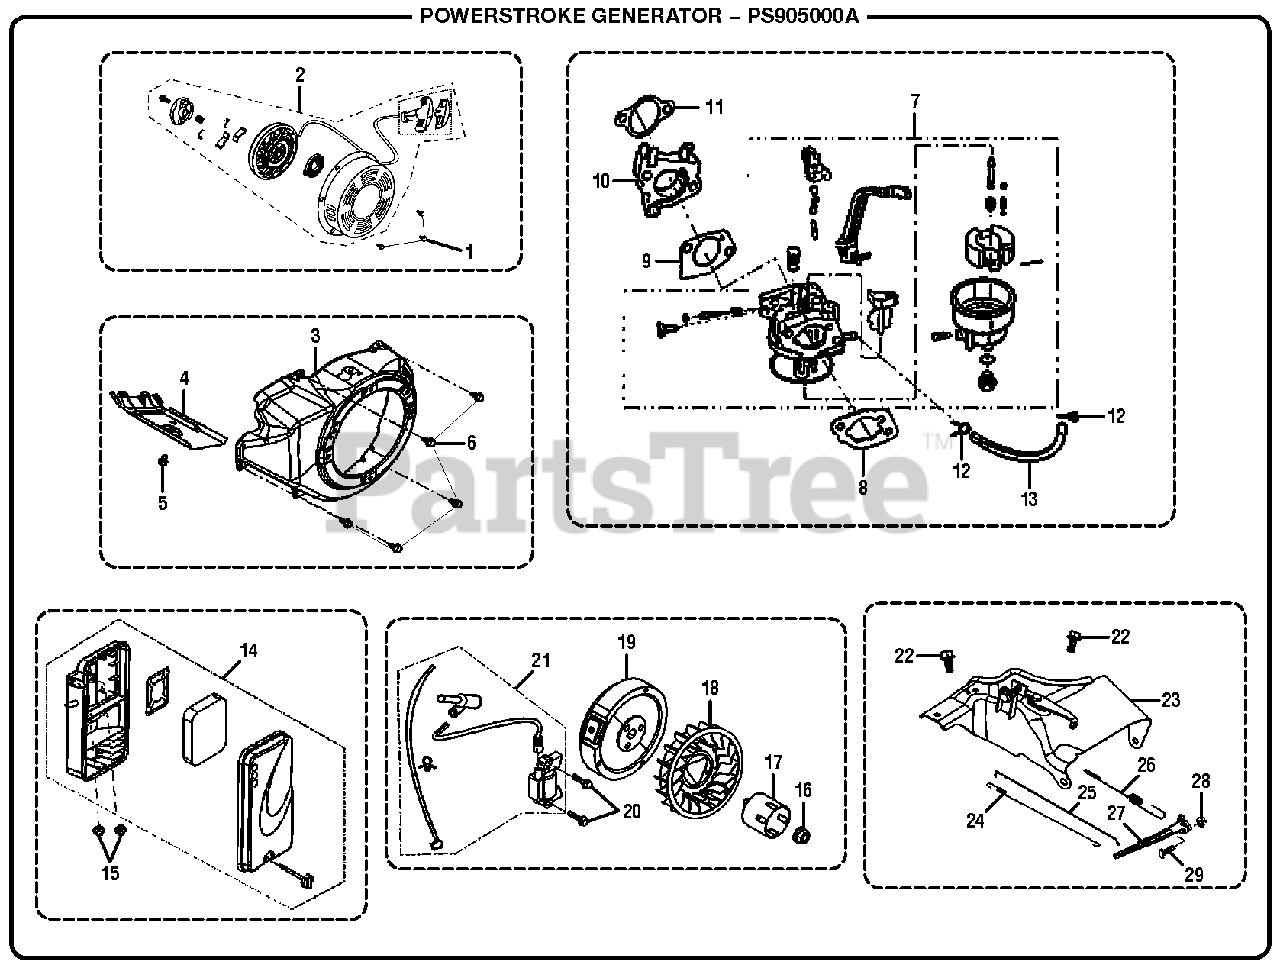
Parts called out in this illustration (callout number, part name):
2	Recoil Starter Assembly
4	Cylinder Body Shroud
7	Carburetor Assembly
8	Air Cleaner Gasket
9	Carburetor Gasket
10	Carburetor Insulator Plate
11	Inlet Gasket
14	Air Cleaner Assembly
16	Flywheel Nut
17	Starter Pulley
19	Flywheel Assembly
21	Ignition Coil
23	Throttle Control Assemby
24	Throttle Valve Return Spring
25	Governor Rod
26	Governor Spring
27	Governor Support Assembly
29	Bolt
